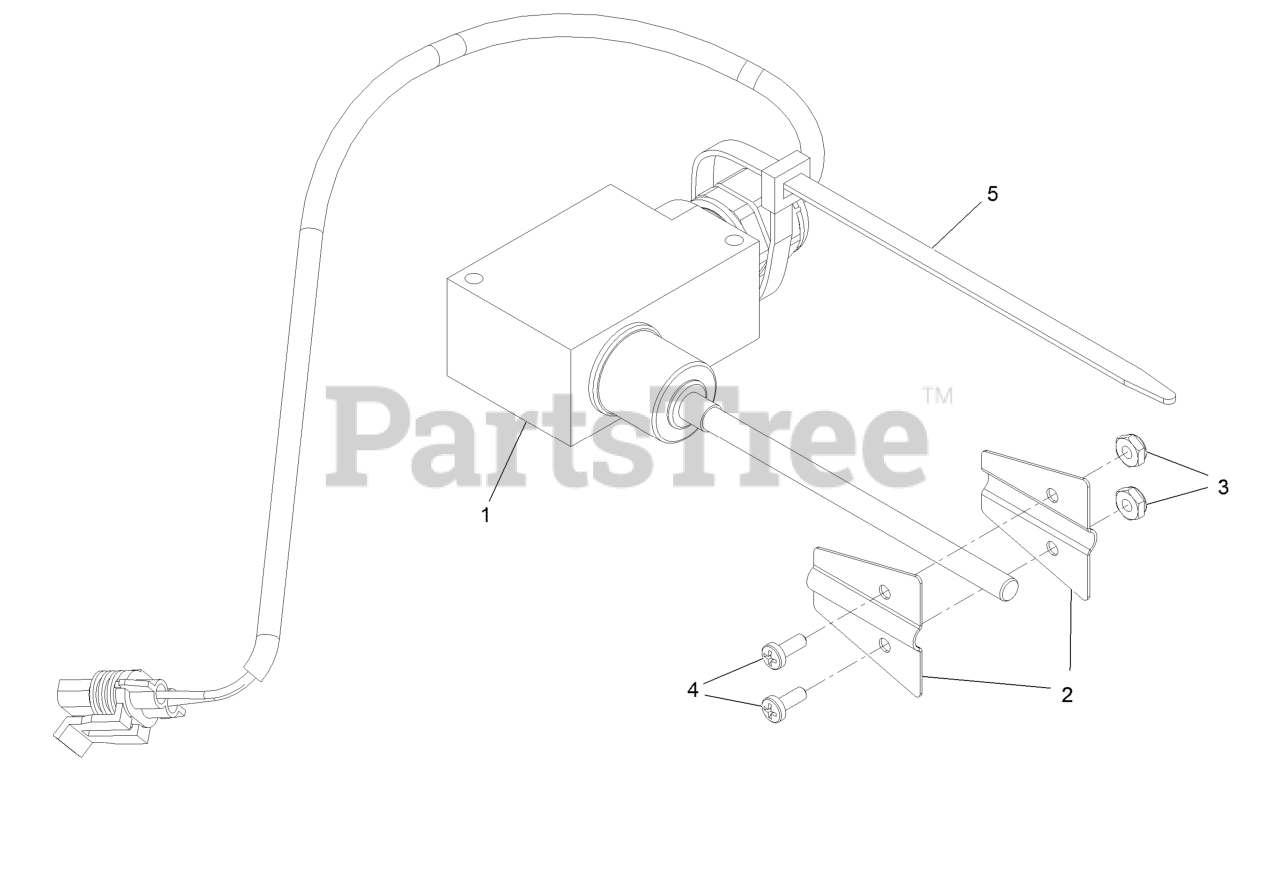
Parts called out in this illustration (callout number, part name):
1	Fill Sensor Wire Kit
2	Flag-Sensor, Fill
3	Nut-Hex
4	Screw-Pan
5	Tie-Plastic
